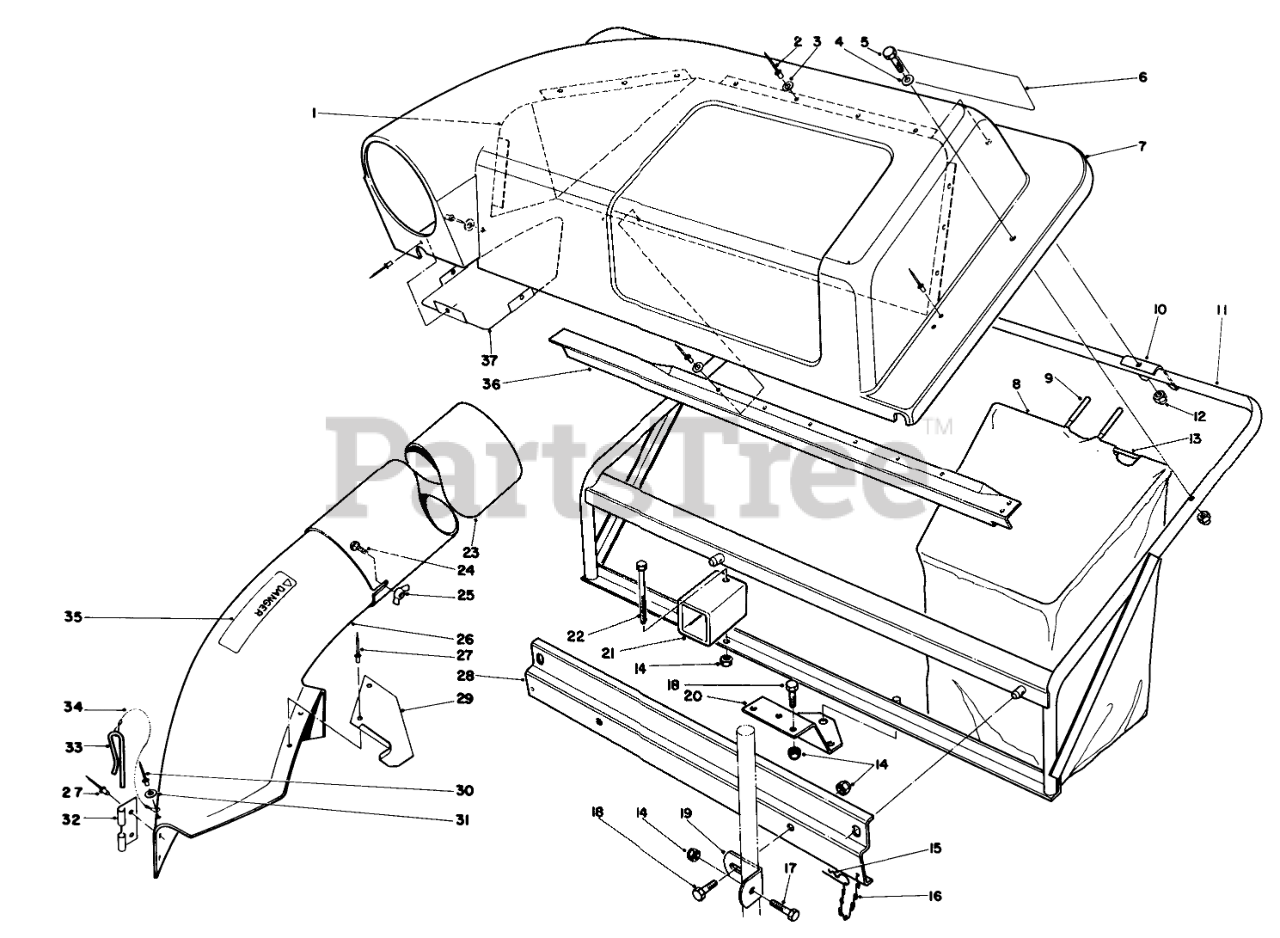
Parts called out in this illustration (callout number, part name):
1	Screen Cover
2	NUT-LOCK
3	WASHER-FLAT
4	WASHER-PLAIN
5	SCREW-HH
6	TWIN BAGGER DECAL
7	Cover
8	Bag-Twin Bagger (Incl. Ref. #9 & 13)
9	GRIP-HANDLE, BAG
10	BAG FRAME BRKT
11	Frame
12	NUT-LOCK, CAP
13	Frame-Bag
14	NUT-LOCK, CONE
15	PIN-HAIR
16	6-LINK CHAIN W/HOOK
17	SCREW-HH
18	SCREW-HH
19	Bracket Mtg. Grass Catcher
20	MTG PLATE B
21	FRAME SUPT TUBE B
22	SCREW-HH
23	TUBE(ROUND&LONG)
24	BOLT-CARR
25	NUT-WING SPECL
26	Chute Assembly (Incl. Ref. #27, 29-35)
27	RIVET-BLIND
28	Bracket Frame Support
29	CHUTE SUPT BRKT
30	RIVET-BLIND
31	WASHER-PLAIN
32	BRACKET-MOUNTING, CHUTE
33	PIN-LOCKING, CHUTE
34	LANYARD
35	Decal-Chute
36	SCREEN SUPT BRKT B
37	Shield Cover
